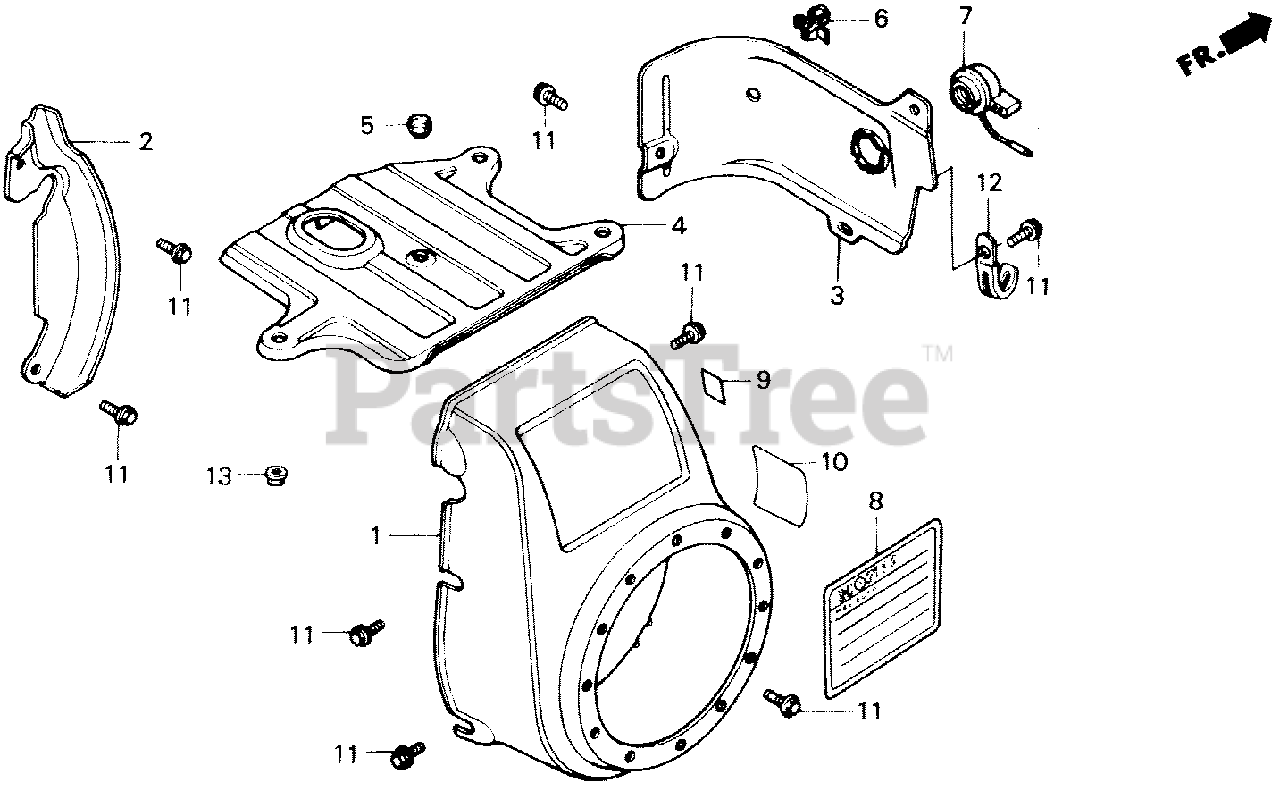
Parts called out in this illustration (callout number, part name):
1	COVER, FAN *R280* (POWER RED)
2	PLATE, SIDE
4	COVER, TOP
5	GROMMET, TOP COVER
7	SWITCH ASSY., ENGINE STOP
9	MARK, C.D.I. SWITCH (NOT AVAILABLE)
10	MARK, OIL CAUTION
11	BOLT, FLANGE (6X12) (CT200)
12	CLIP, WIRE
13	NUT, FLANGE (6MM)
